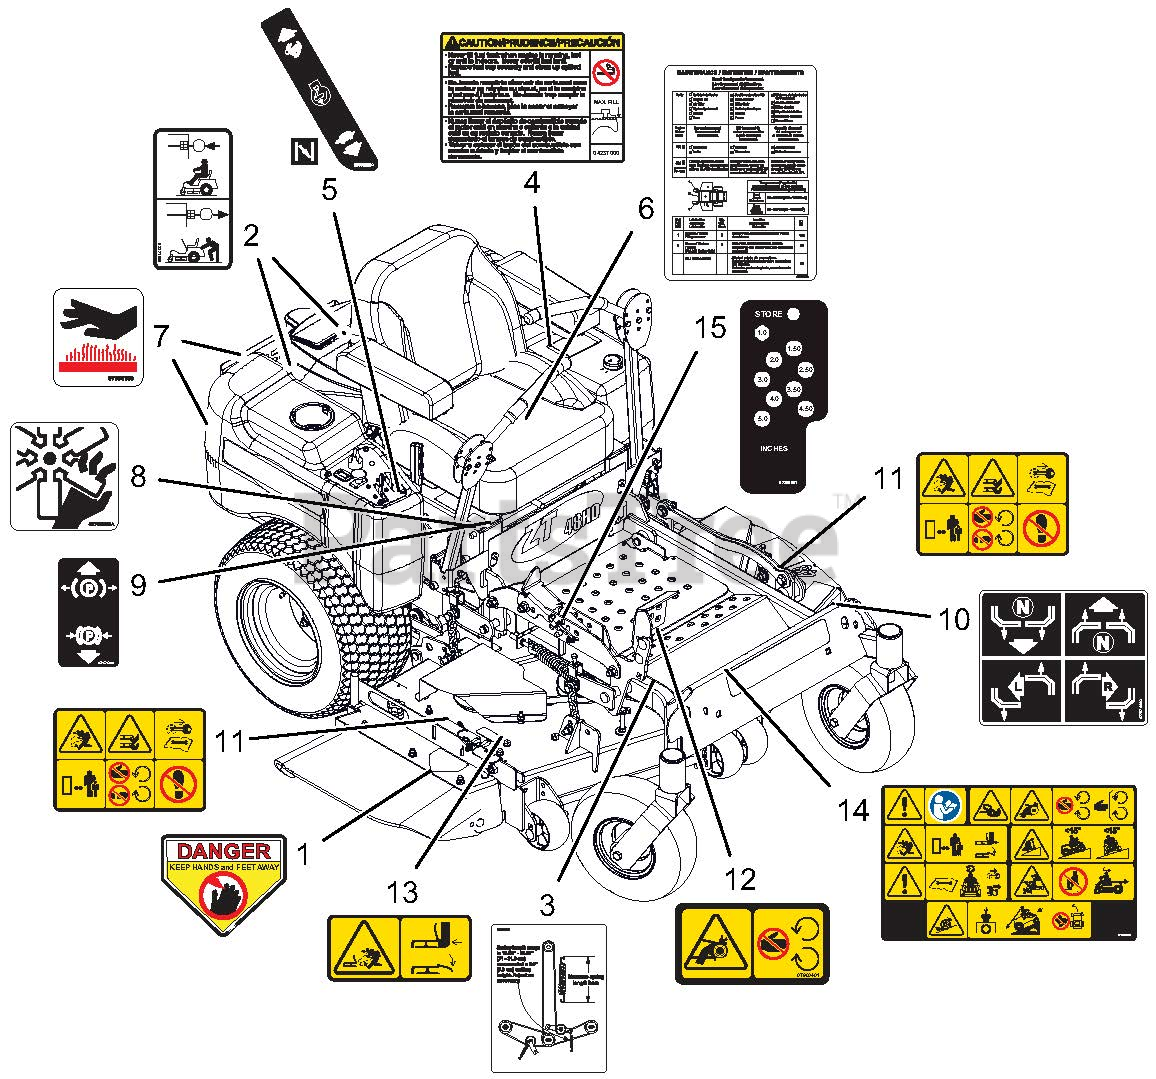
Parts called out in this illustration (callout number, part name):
1	DECAL, DANGER
2	DECAL, TRANSMISSION DISCONNECT
3	DECAL, BELT ROUTING
4	DECAL, FUEL WARNING
5	DECAL, SPEED CONTROL
6	DECAL, MAINTENANCE INSTRUCTIONS
7	DECAL HOT SURFACE
8	DECAL, DANGER - FAN
9	DECAL, PARKING BRAKE LEVER
10	DECAL, INSTRUCTIONAL - STEERING
11	DECAL, SAFETY - MOWER DECK
12	DECAL, SAFETY - GUARDING
13	DECAL, SAFETY - DECK GUARDING
14	DECAL, MAIN SAFETY, COMMERCIAL
15	DECAL, HD HEIGHT OF CUT
